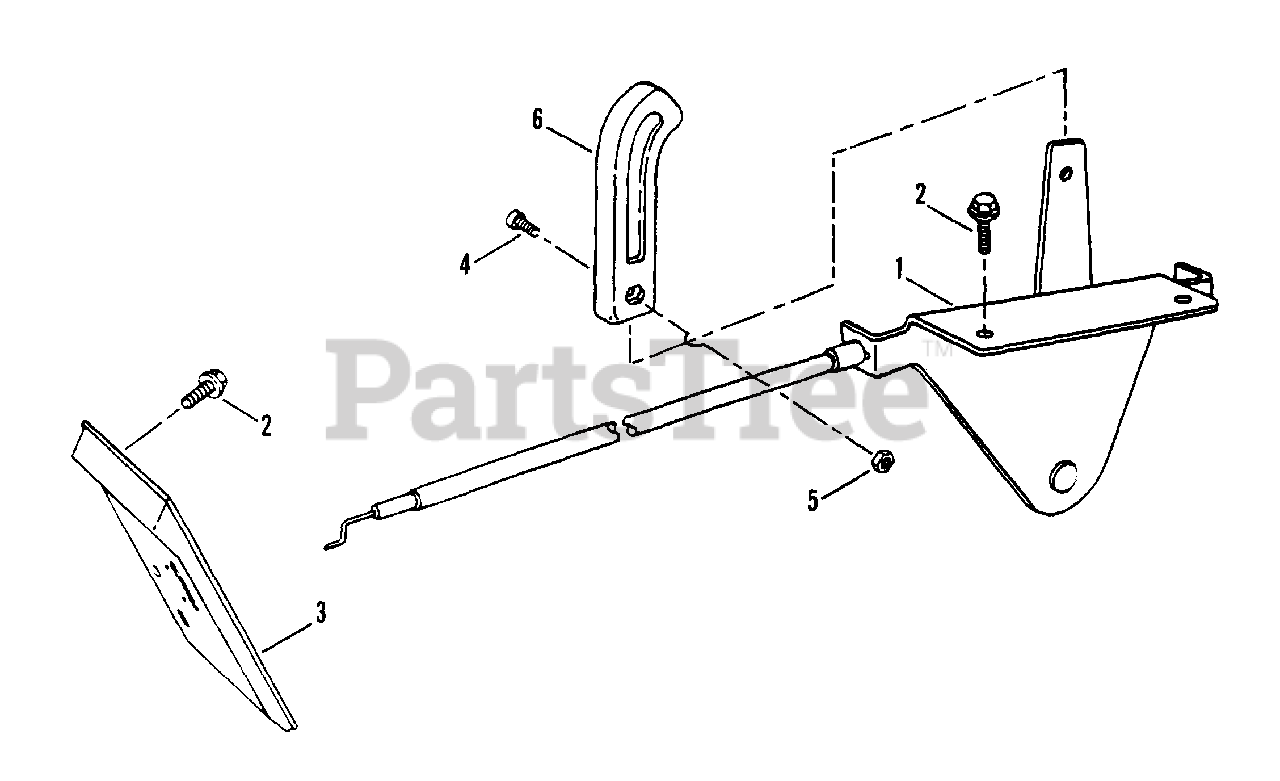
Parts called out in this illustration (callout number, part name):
1	CONTROL, Throttle (Briggs)
2	SCREW, #10-24 x 1/2" Hex Washer Self-Tap (Torx)
3	COVER, Dash Panel (Electric Start)
4	SCREW, #8-32 x 3/8" Cross Recessed Fillister Head
5	NUT, #8-32 Hex
6	KNOB, Throttle Control
